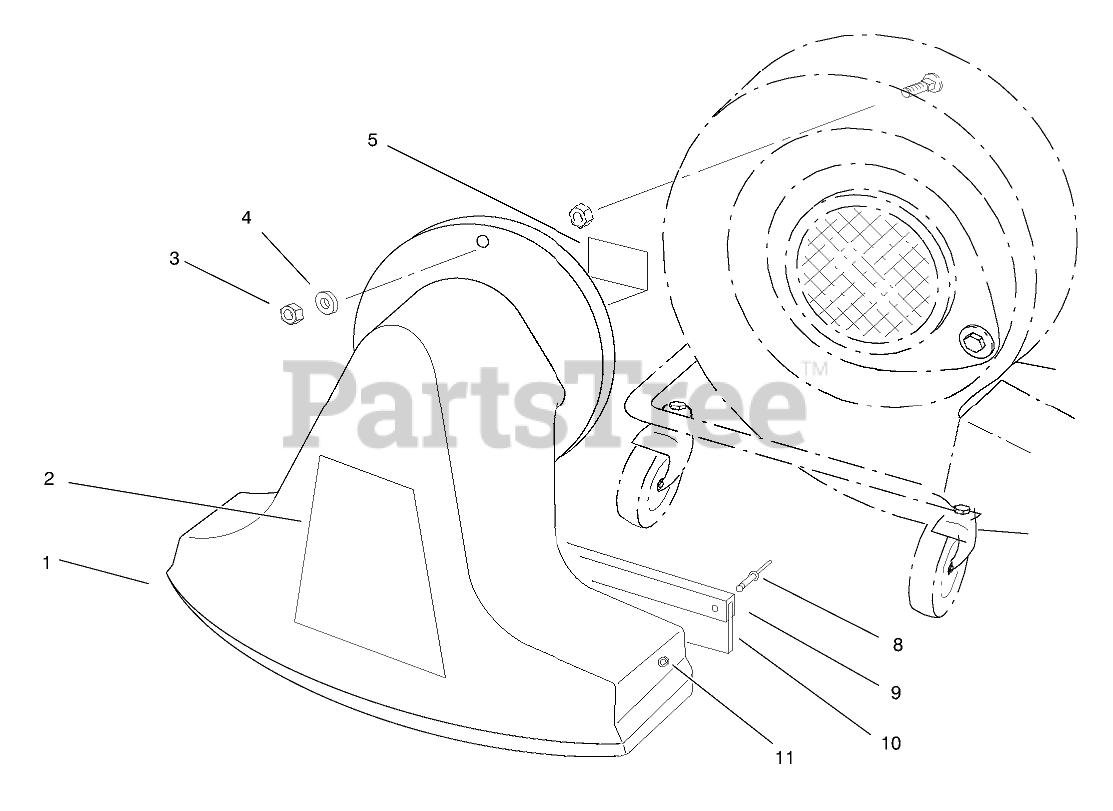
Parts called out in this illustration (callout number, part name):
1	Snout Assembly (Incl. Ref. #1, 8-10)
2	DECAL-VACUUM SP
3	NUT-LOCK, NI
4	WASHER
5	DECAL-CAUTION, BAG
8	RIVET-POP
9	Clamp-Flap
10	FLAP-RUBBER
11	WASHER-FLAT
